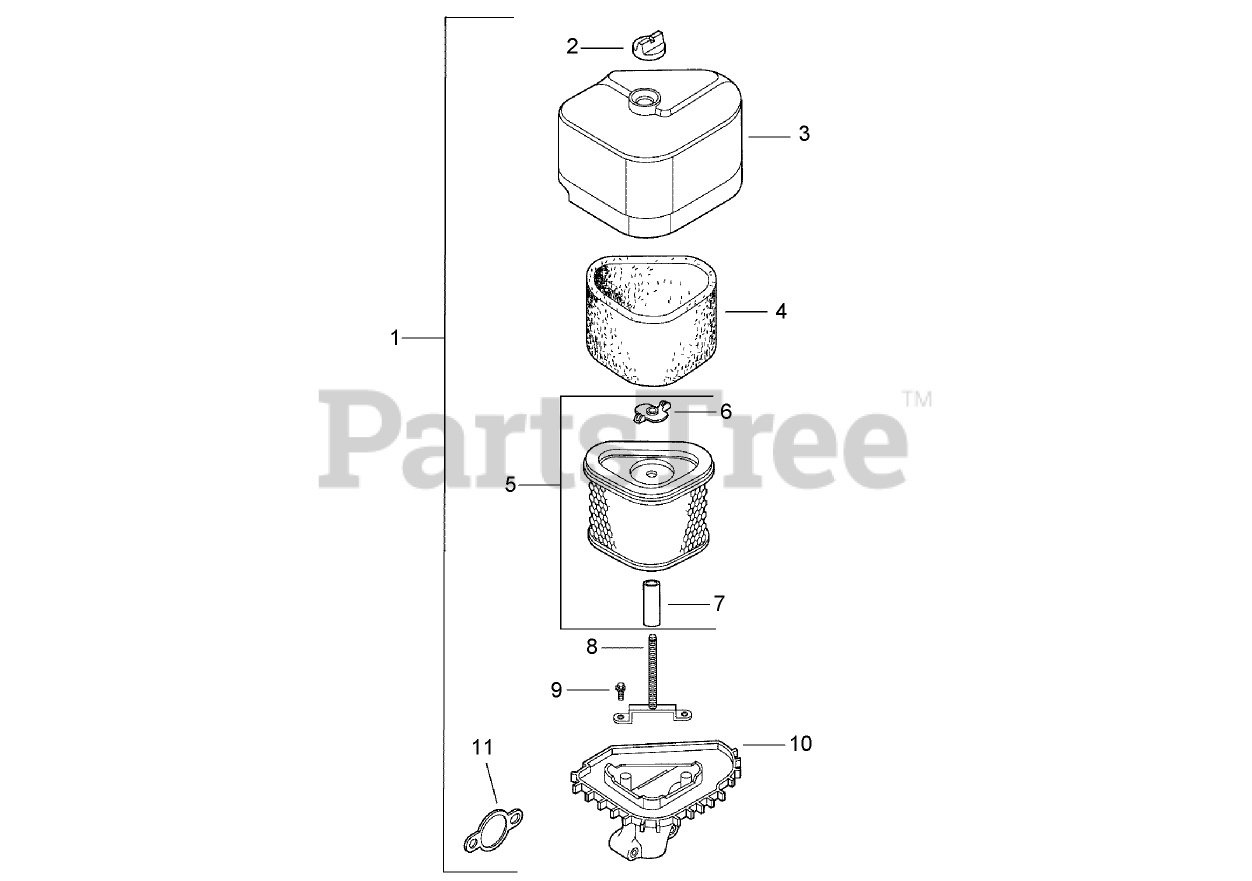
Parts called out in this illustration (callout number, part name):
1	Air Cleaner Kit (Incl. Ref. #2-11)
2	KNOB-COVER
3	Cover-Cleaner, Air
4	Element-Precleaner
5	Element-Cleaner, Air (Incl. Ref. #6)
6	NUT-WING
7	Seal
8	Stud
9	Screw
10	Base-Cleaner, Air
11	Gasket-Base, Air Cleaner
